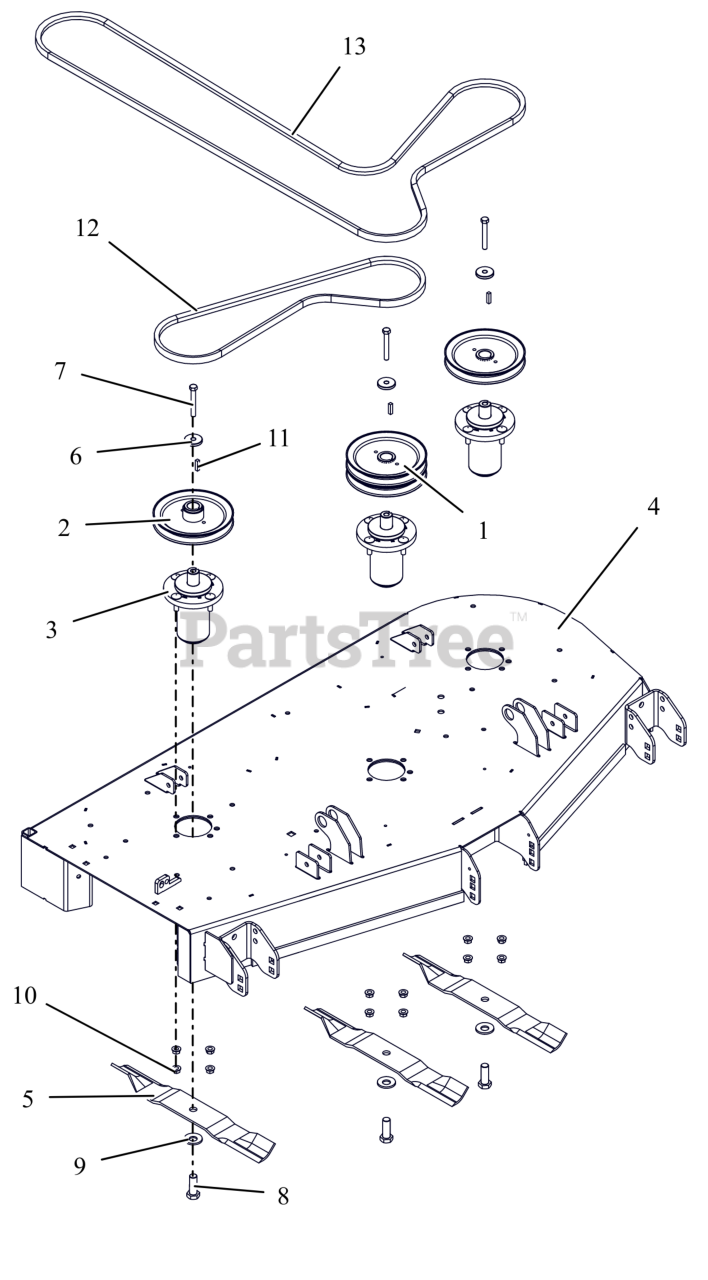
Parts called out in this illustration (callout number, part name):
1	PULLEY, DOUBLE 1.000 ID X 6.750 OD-BLACK
2	PULLEY, V-1.000 ID X 6.750 OD
3	ASM, MAINT FREE ALUM SPINDLE
4	KIT-DECK-52" W/DECALS-ARIENSCE
5	BLADE, 18"
6	RETAINER, SHEAVE
7	BLT, HEX .38-16X2.75 G8 ZCC
8	BLT, HEX .62-18X1.75 G8 ZCC
9	WSHR-BLVL .669X1.535X.138
10	NUT-LK-CTR-FLG .375-16 GF ZCC
11	KEY, SQ .25X.25X1.00 RC 40-50
12	V-BELT, B-COGGED
13	V-BELT, HB SECTION
